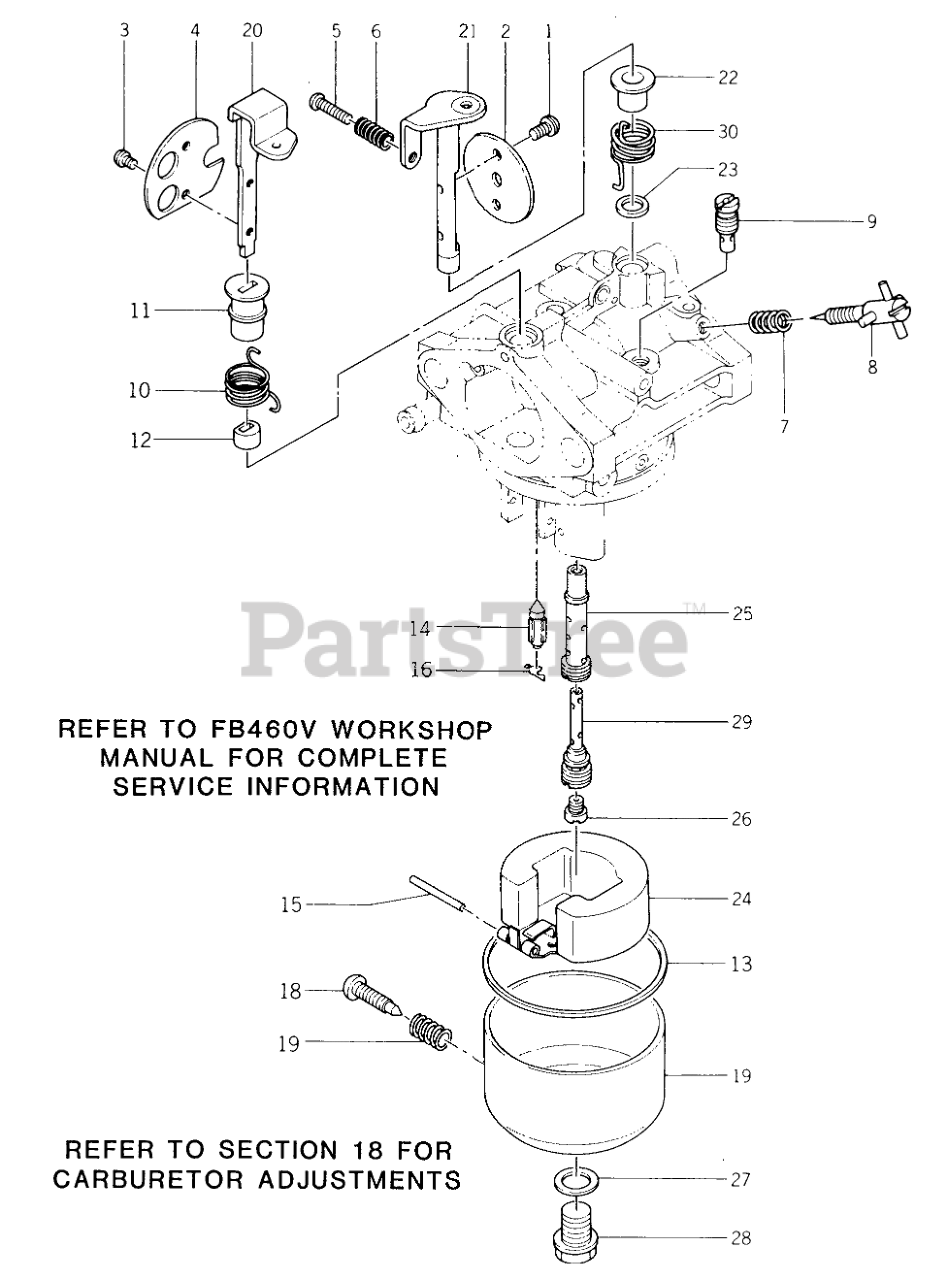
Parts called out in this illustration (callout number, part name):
2	Throttle Valve (#120)
4	Choke Valve
9	Pilot Jet (#62.5)
12	Ring
13	Gasket
14	Valve-Float
15	Pin
17	Float Chamber Assy (includes items 18 & 19)
18	Screw
20	Shaft-Choke
21	Shaft-Throttle
28	Bolt
29	Pipe-Bleed
31	Carburetor Gasket Set
